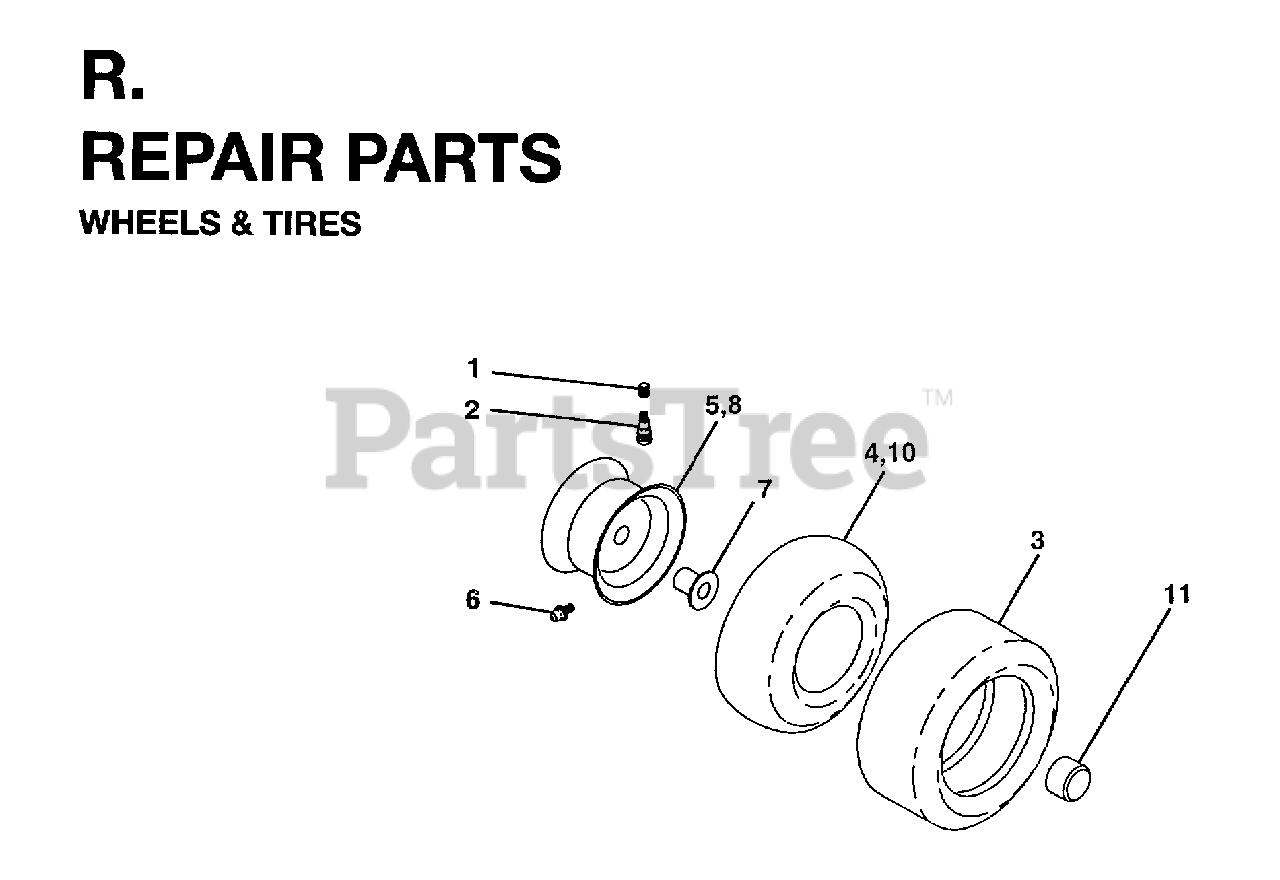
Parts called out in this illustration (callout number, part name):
1	VALVE CAP
2	VALVE STEM LT
3	TIRE
4	TUBE.5.3/4.5/6
5	RIM ASM 6" FRONT SILVER
6	FITTING LT
7	BEARING T
8	RIM 8" SILVER
10	TUBE - UNIVERSAL FOR 8" RIM
11	CAP-HUB FRONT LT
